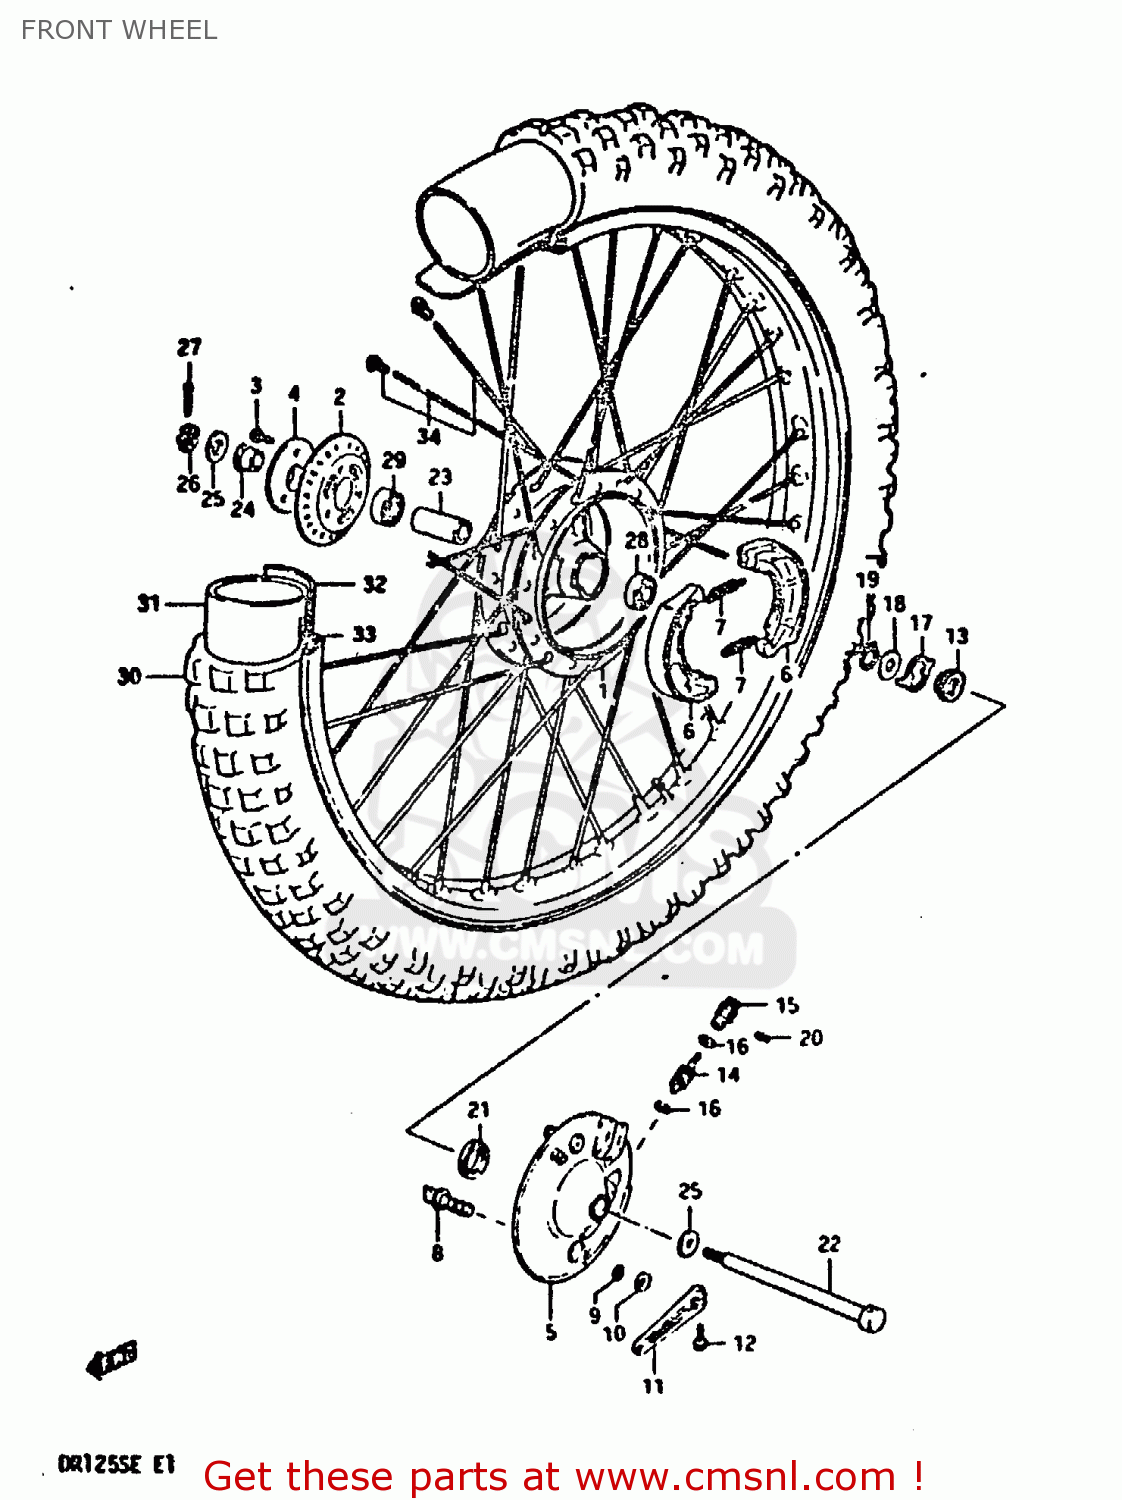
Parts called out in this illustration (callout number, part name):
1	HUB,FR WHEEL
2	FLANGE,FR HUB,R
3	BOLT
4	PLATE,FRONT HUB BEARING
5	PANEL,FRONT HUB
6	SHOE,BRAKE
7	SPRING(L:34)
8	CAM,FRONT BRAKE
9	O-RING (D:2.4 ID:13.8)
10	WASHER (14.5X22X1.6)
11	LEVER,FRONT BRAKE CAM
12	BOLT
13	GEAR,SPEEDOMETER
14	PINION,SPEEDOMETER
15	BUSH,METER GEAR OUTER
16	WASHER (5.1X9X0.4)
17	DRIVER,SPEEDOMETER GEAR
18	WASHER(18.5X24X1)
19	CIRCLIP
20	SCREW
21	OIL SEAL (43X58X7)
22	AXLE,FRONT
23	SPACER (12.6X19X52)
24	SPACER,FR AXLE,R
25	WASHER
26	NUT 12MM
27	COTTER PIN
28	BEARING
29	BEARING, RH
30	TIRE,FRONT
31	TUBE
32	PROTECTOR,WHEEL,INNER
33	RIM,FRONT WHEEL (GOLD)
34	SPOKE ASSY,FR WHEEL
